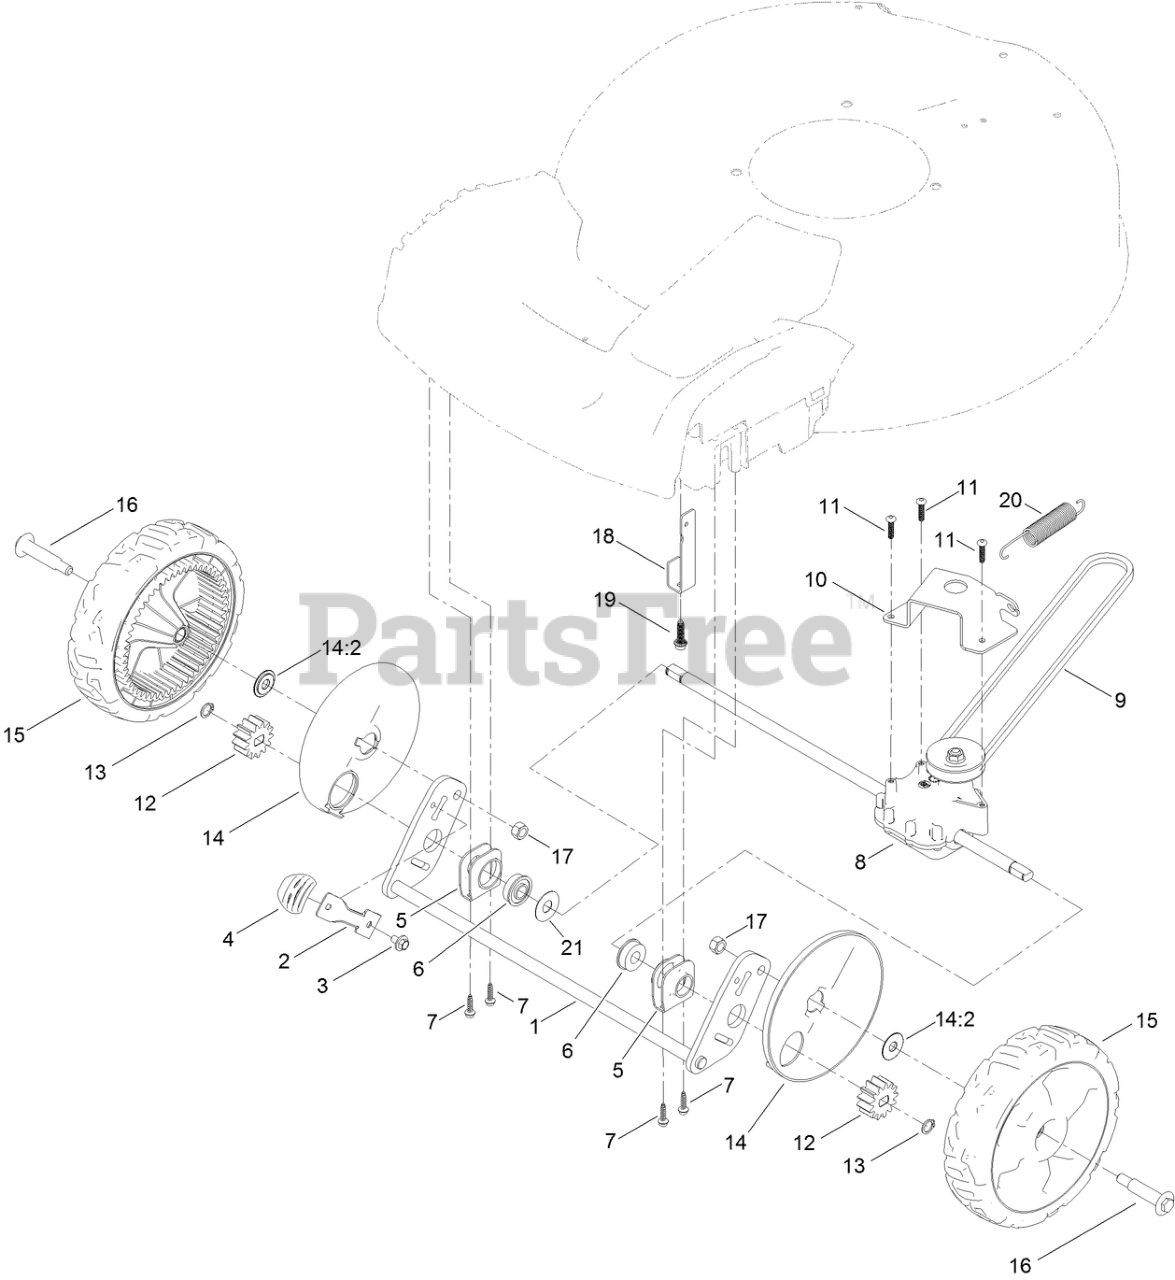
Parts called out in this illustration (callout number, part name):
2	ARM-SPRING
3	SCREW AND WASHER ASM
4	KNOB-LEVER, HOC
5	RETAINER-BEARING
6	BEARING-BALL
7	SCREW-HWH
8	TRANSMISSION-FWD LB, 2BAIL (6:1)
10	BRACKET-TRANSMISSION
11	SCREW-PLASTITE
12	GEAR-PINION, 13T
13	RING-RETAINING
14	WHEEL COVER ASM
14:2	WASHER-STEPPED
15	WHEEL ASM, 8IN
16	BOLT-SHOULDER
17	NUT-HEX
18	BRACKET-ANCHOR, CABLE
19	SCREW-FLANGE, PLASTIC
20	SPRING-EXTENSION
21	WASHER-PLAIN
